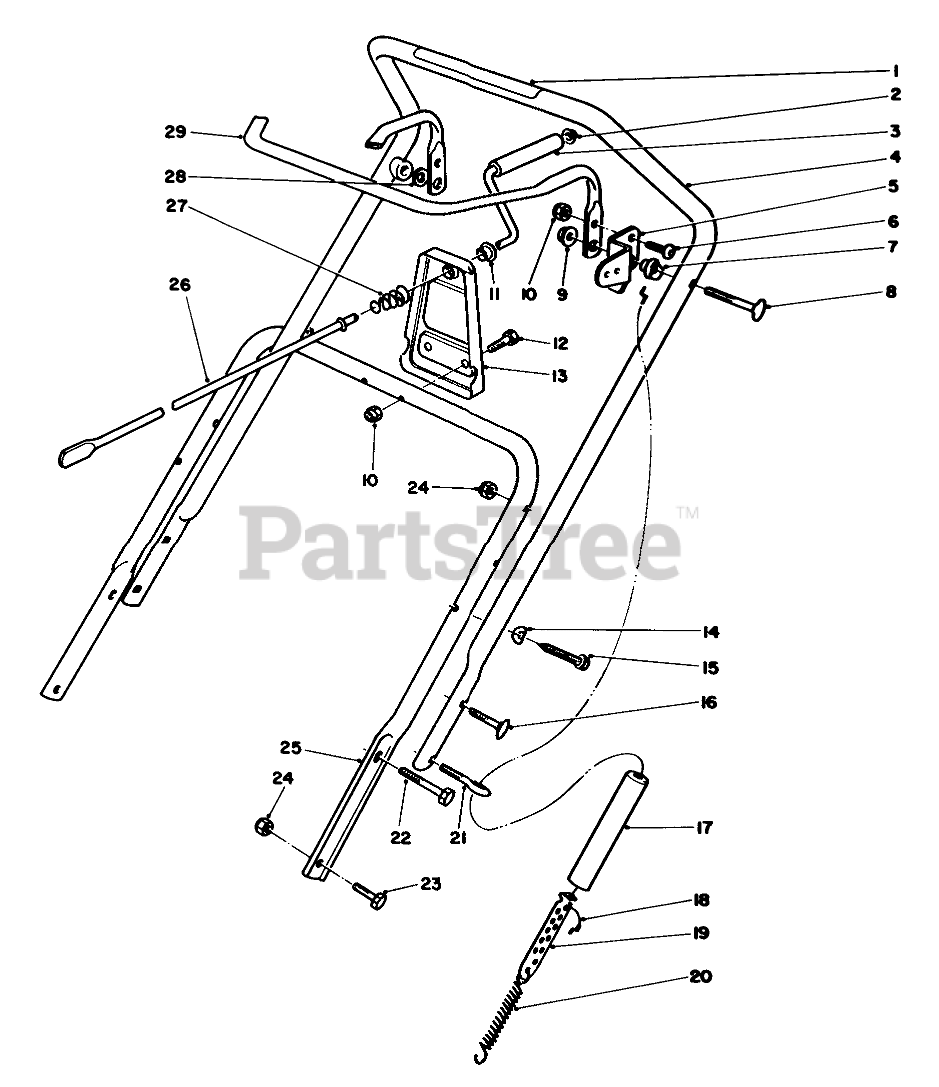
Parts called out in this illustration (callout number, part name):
1	DECAL - ROTOR DRIVE
2	RETAINER-PUSH ON
3	Grip-Rod
4	Upper Handle Assembly (Incl. Ref. #1)
5	Arm-Clutch Cable
6	SCREW-HSBH
7	SPACER-BAR, CONTROL
8	SCREW
9	NUT-LOCK, CAP
10	NUT-LOCK, NI
11	Bushing
12	SCREW-HH
13	Support-Crank
14	WASHER
15	SCREW
16	SCREW
17	COVER-SPRING
18	CABLE-CLUTCH
19	ADJUSTER-CABLE
20	SPRING-EXTENSION
21	BOLT-EYE
22	SCREW-HH
23	SCREW-HH
24	NUT-LOCK, NI
25	LOWER HANDLE
26	ROD-CRANK, CHUTE
27	SPRING-COMPRESSION
28	WASHER
29	Bar-Control
